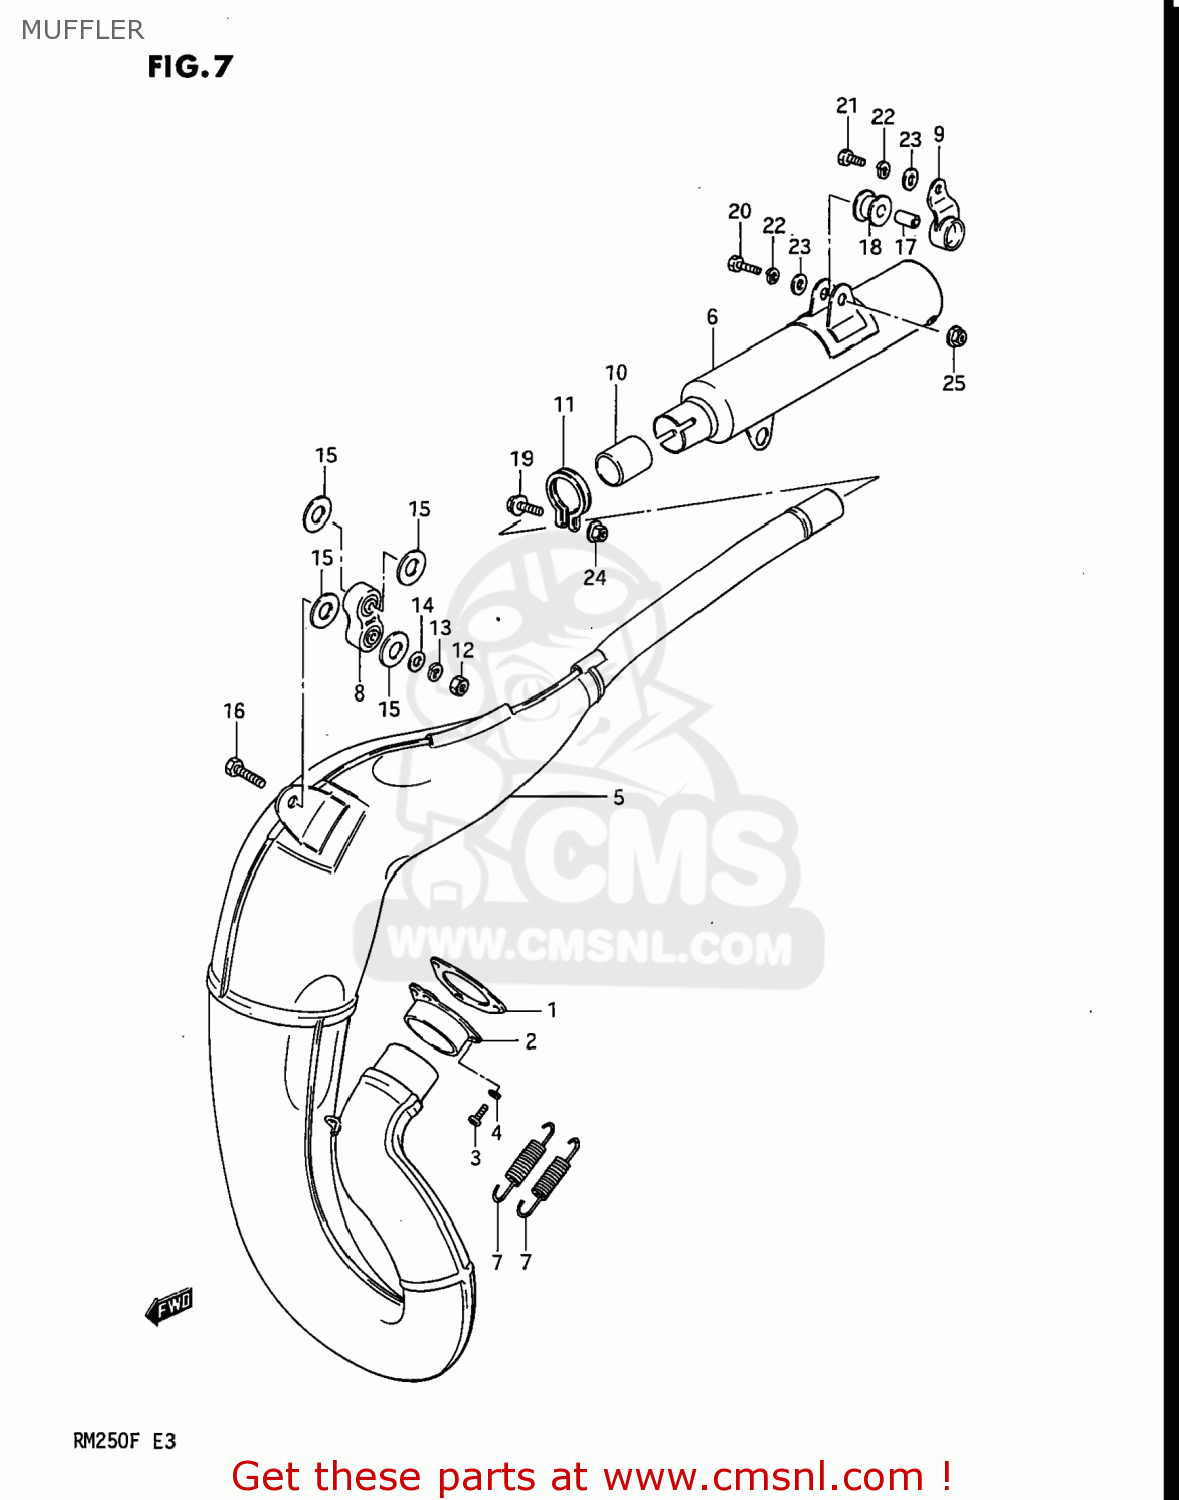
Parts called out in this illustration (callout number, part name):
1	GASKET,EXHAUST PIPE (MCA)
2	FLANGE,EXHAUST PIPE
3	SCREW
4	LOCK WASHER
5	BODY,MUFFLER
6	BODY,MUFFLER
7	SPRING
8	DAMPER,MUFFLER
9	DAMPER,MUFFLER SUPPORT
10	CONNECTOR,MUFFLER
11	CLAMP,MUFFLER 2ND
12	NUT 8MM
13	LOCK WASHER
14	WASHER
15	WASHER(13X28X1.6)
16	BOLT(8X32)
17	SPACER (8.6X12X17.5)
18	CUSHION
19	BOLT
20	BOLT
21	BOLT
22	LOCK WASHER
23	WASHER
24	NUT 6MM
25	NUT
